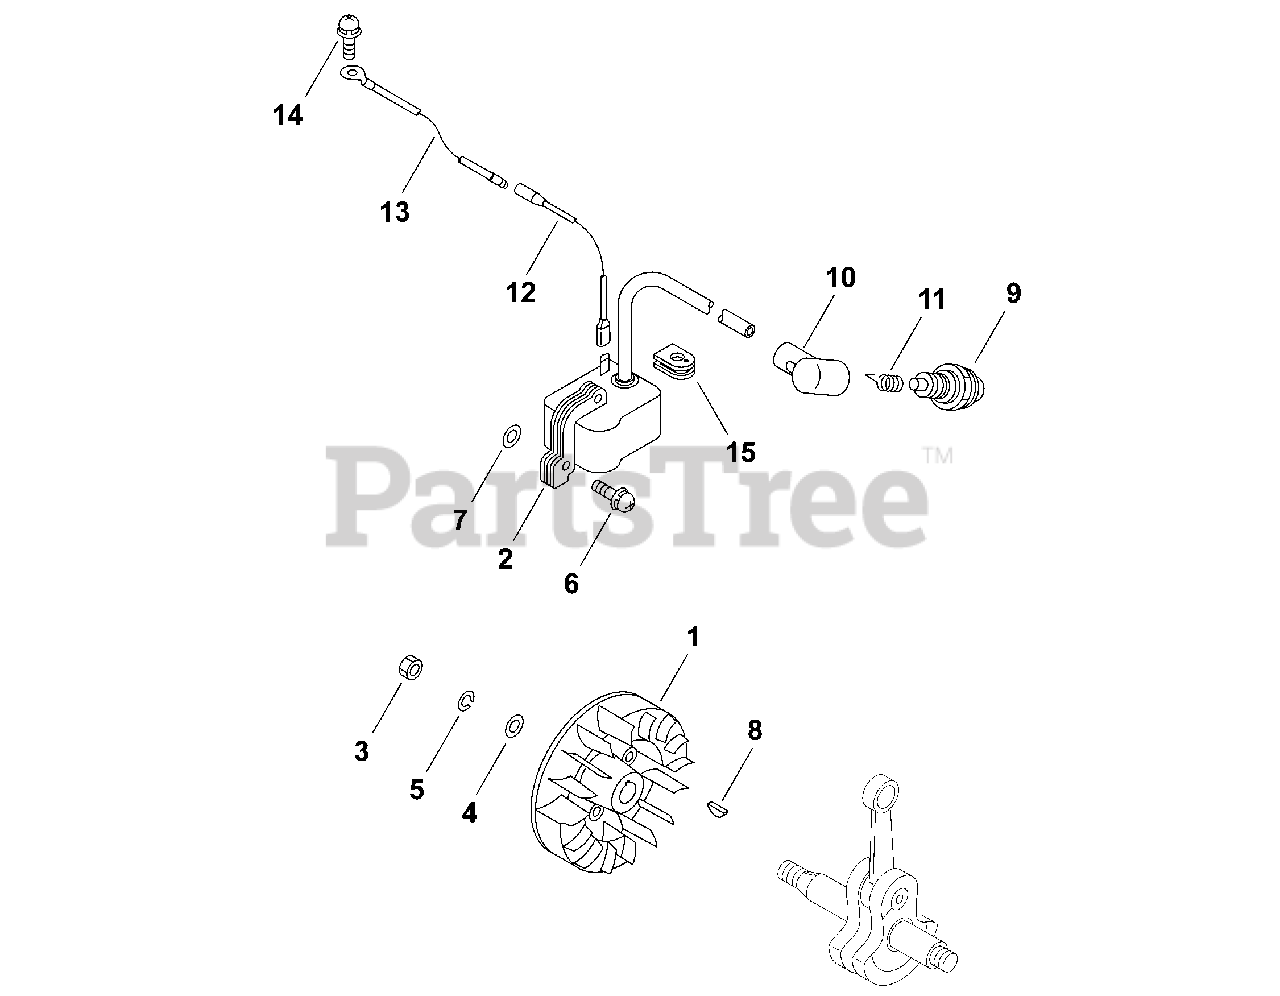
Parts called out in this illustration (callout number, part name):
1	FLYWHEEL
2	COIL, IGNITION
3	NUT 10×1.25
4	WASHER 10.5×18×1.6
5	WASHER, SPRING 10
6	SCREW 5×20
7	WASHER 6.5×11.5×0.8
8	KEY, WOODRUFF
9	SPARK PLUG - BPM7A
10	CAP, SPARK PLUG
11	TERMINAL, SPARK PLUG
13	LEAD - GROUND
14	SCREW 5×10
